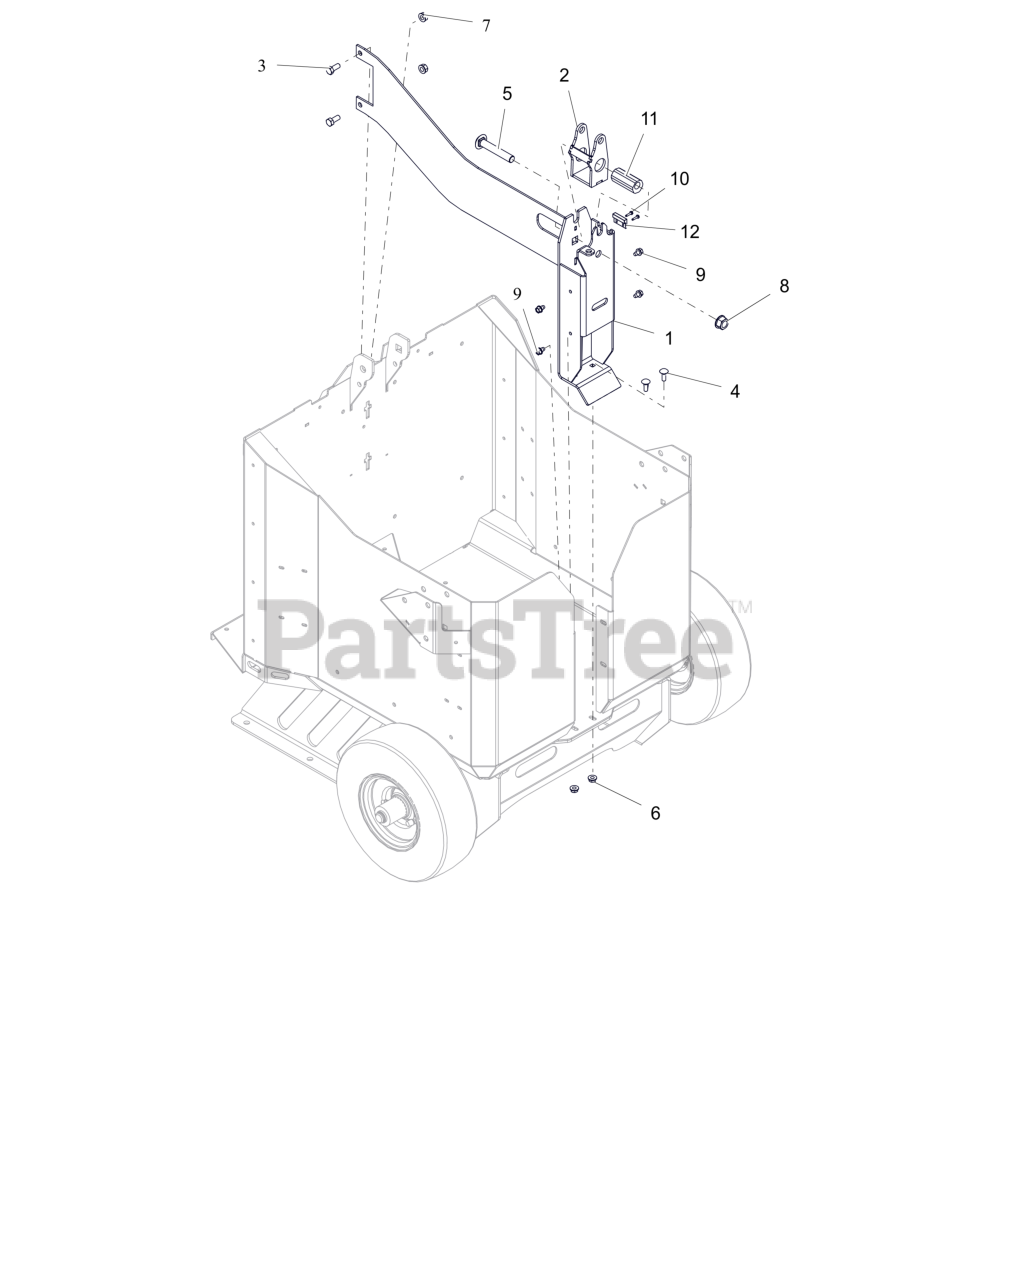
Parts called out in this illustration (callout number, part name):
1	WLDMT, MTG ECCENTRIC (OBC) (BLACK)
2	WLDMT, ECCENTRIC
3	BLT,HEX .31-18X.75 G5 ZCC
4	BLT, RHSN .25-20X.750 G5 ZCC
5	BTL,RHSSN .500-13 X 3 G5 ZCC
6	NUT-SPNLK-FLG .25-20 ZC120
7	NUT,LK-CTR-FLG .31-18 GF ZCC
8	NUT-LK-CTR-FLG .500-13 GG ZCC
9	SCR,TAP .25-20X.375 HWH TR ZCC
10	SCR-TAP #4-40X.50 HWH ZCC
11	ECCENTRIC, HOOD LATCH
12	SWITCH, MAGNET (NO WIRE)
